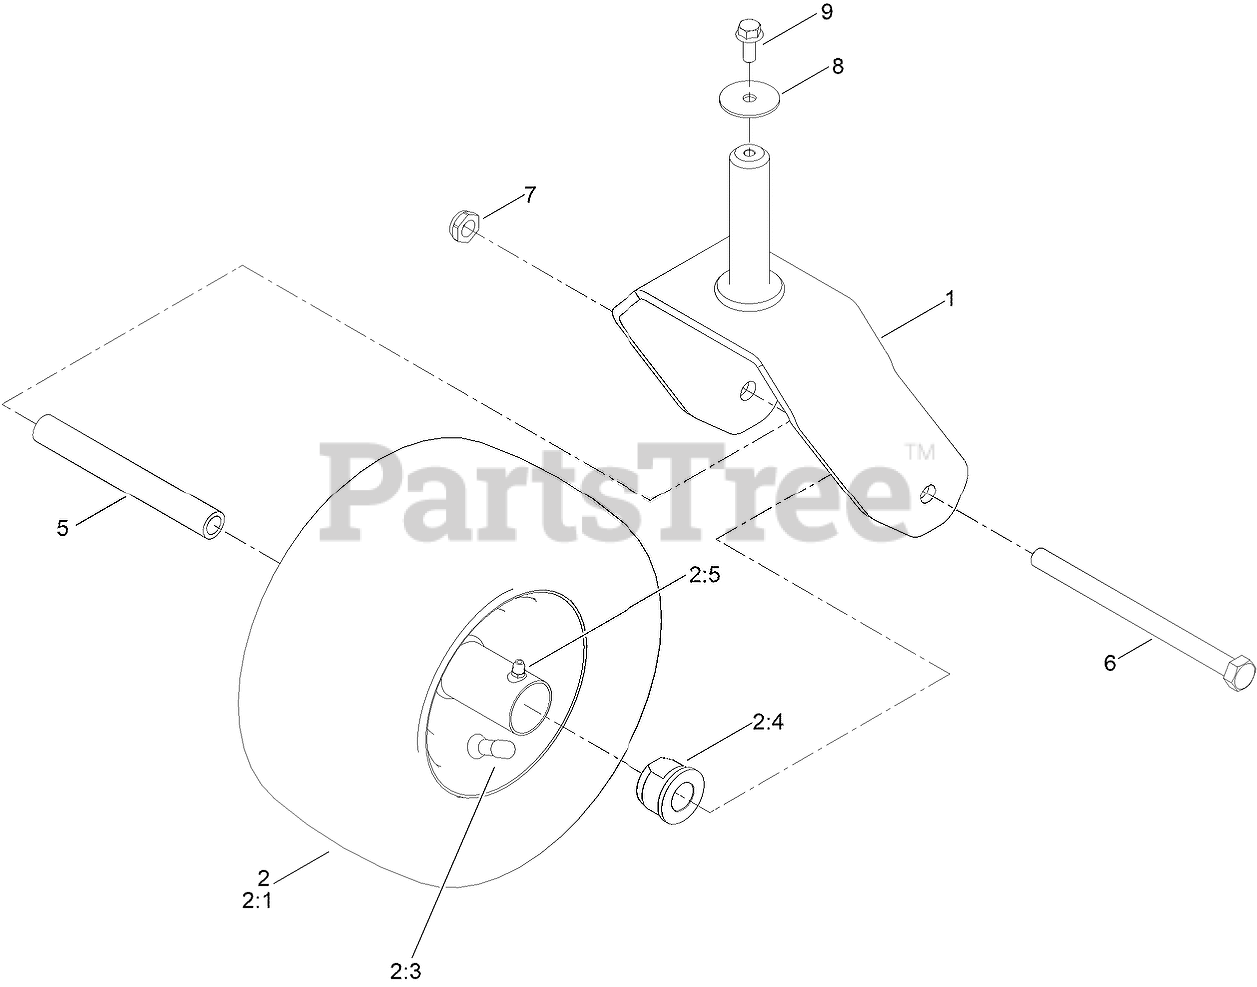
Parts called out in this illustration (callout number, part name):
1	FORK ASM
2	TIRE ASM
2:4	BUSHING-FLANGE
2:5	FITTING-GREASE
5	SPACER-SPANNER
6	SCREW-HH
7	NUT-HEX
8	WASHER-FLAT
9	SCREW-HHF
